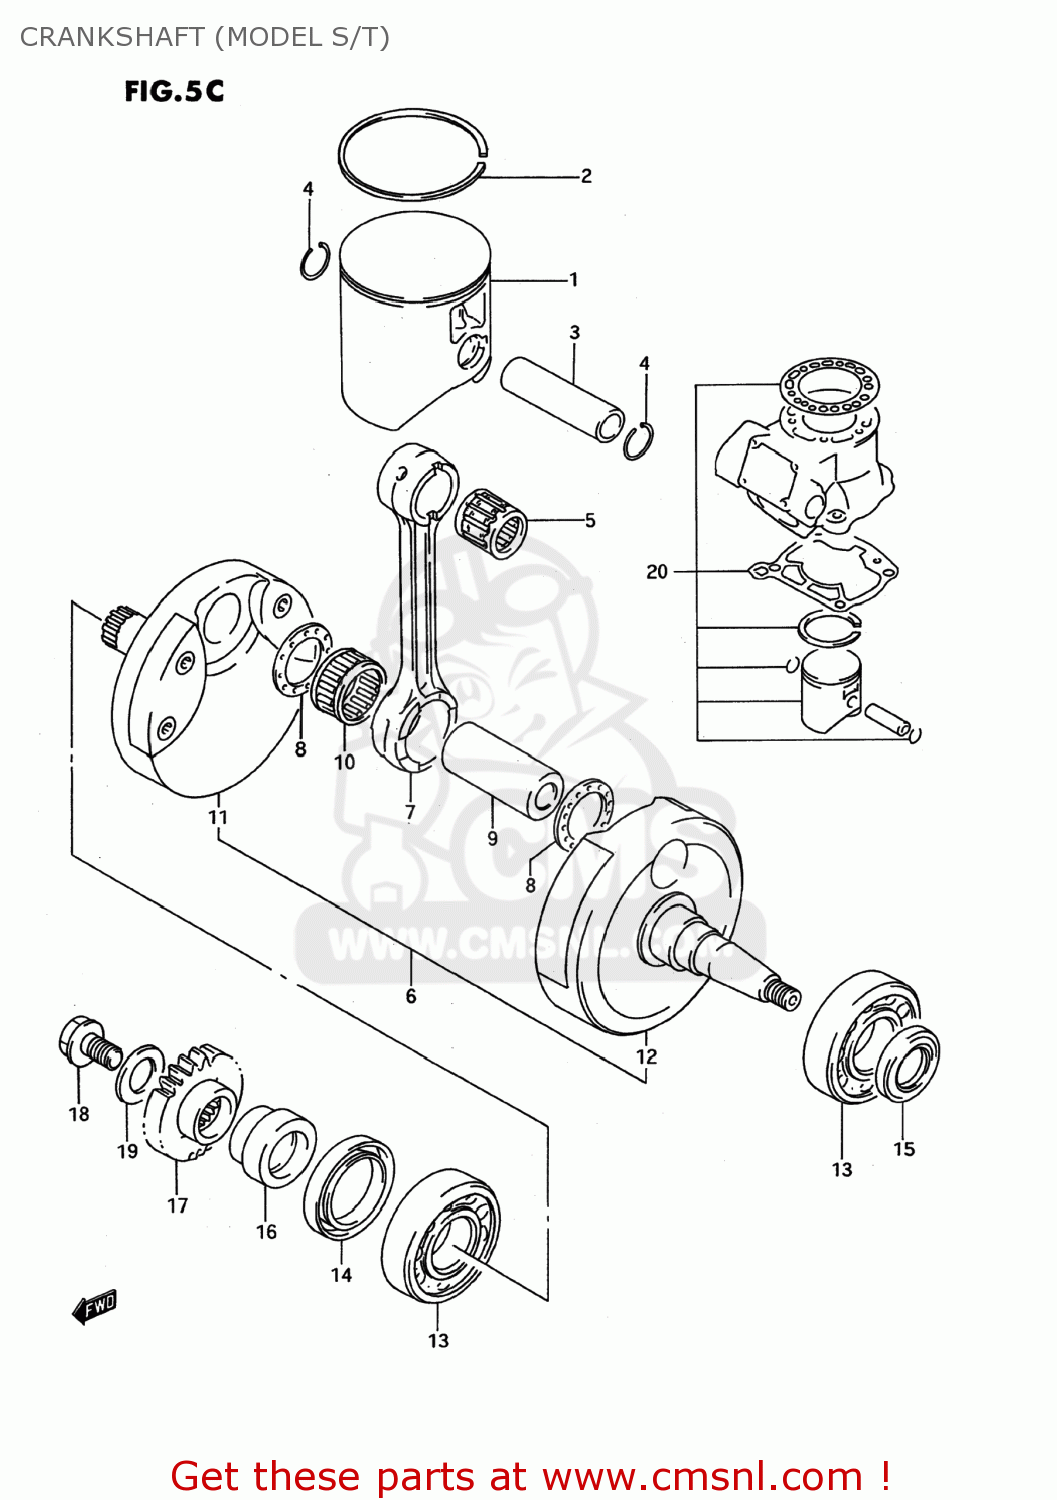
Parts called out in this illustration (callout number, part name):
1	PISTON
2	RING,PISTON
3	PIN,PISTON
4	CIRCLIP
5	BEARING(18X23X22)
6	CRANKSHAFT ASSEMBLY
7	ROD,CONNECTING
8	WASHER(24X38.5X1.5)
9	PIN,CRANK
10	BEARING(24X30X20)
11	CRANKSHAFT,R
12	CRANKSHAFT COMP,LEFT
13	BEARING
14	SEAL,OIL(38X52X8)
15	SEAL,OIL(25X37X6)
16	SPACER,PRIMARY DRIVE GEAR
17	GEAR,PRIMARY DRIVE (NT:
18	BOLT,PRIMARY DRIVE GEAR
19	WASHER
20	TOP END KIT,ENGINE
